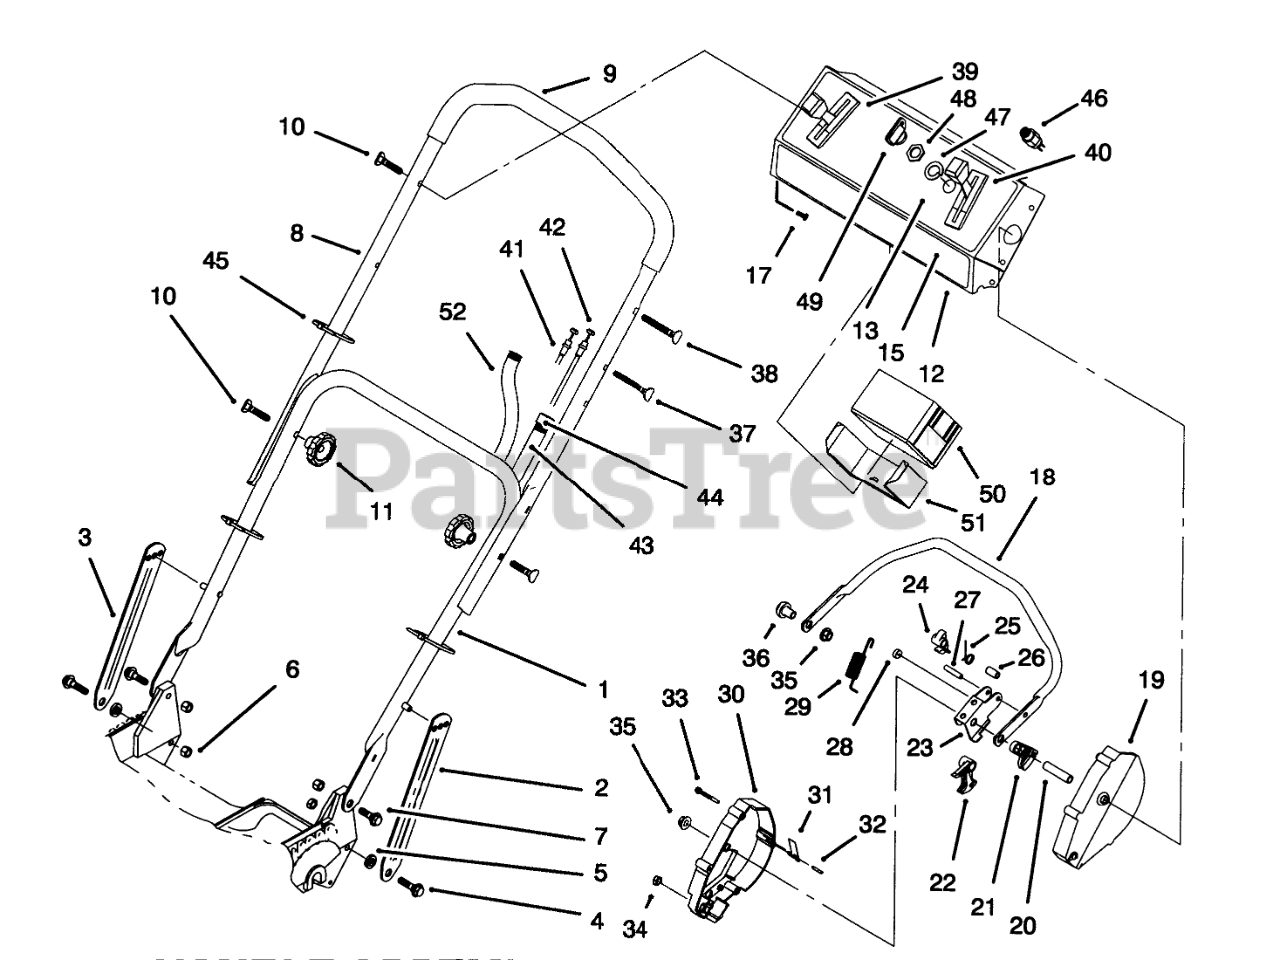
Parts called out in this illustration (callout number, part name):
1	ASM-Handle
2	Latch-Handle
3	Latch-Handle
4	SCREW-SHOULDER
5	SPACER
6	NUT-LOCK, NI
7	SCREW-SHOULDER
8	Handle-Upper
9	Grip-Foam
10	SCREW-HANDLE
12	Panel-Control (Incl. Ref. #13)
13	DECAL - INSTRUCTION
15	DECAL - FRT PANEL
17	SCREW-TAP
18	Bar-Control
19	HOUSING-CONTROL, LH
20	TUBING-SPACER
21	LEVER-TRACTION
22	ROCKER
23	LEVER-CABLE
24	HOOK-CONTROL
25	SPRING-TORSION
26	SPACER
27	PIN-ROLL, SLOTTED
28	WASHER-NYLON
29	SPRING-DETENT
30	Housing-Control
31	SPRING-LEAF
32	PIN-INSERT
33	SCREW-HWHTF
34	NUT-LOCK NI
35	NUT-LOCK NI
36	SPACER-SUPPORT
37	SCREW-HANDLE
38	OBS MATERIAL EXCEPT FOR SERVICE
39	CONTROL-SPEED, GROUND
40	THROTTLE CONTROL
41	CLUTCH CABLE
42	TRACTION CABLE
43	CONTROL CABLE COVER
44	FITTING-RING
45	TIE-CABLE
46	Switch-Starter (Incl. Ref. #47 & 48)
47	WASHER-TOOTH, INTERNAL
48	NUT-HH
49	KEY-IGNITION
50	BATTERY ASSEMBLY
51	Retainer-Battery
52	Harness-Wire
